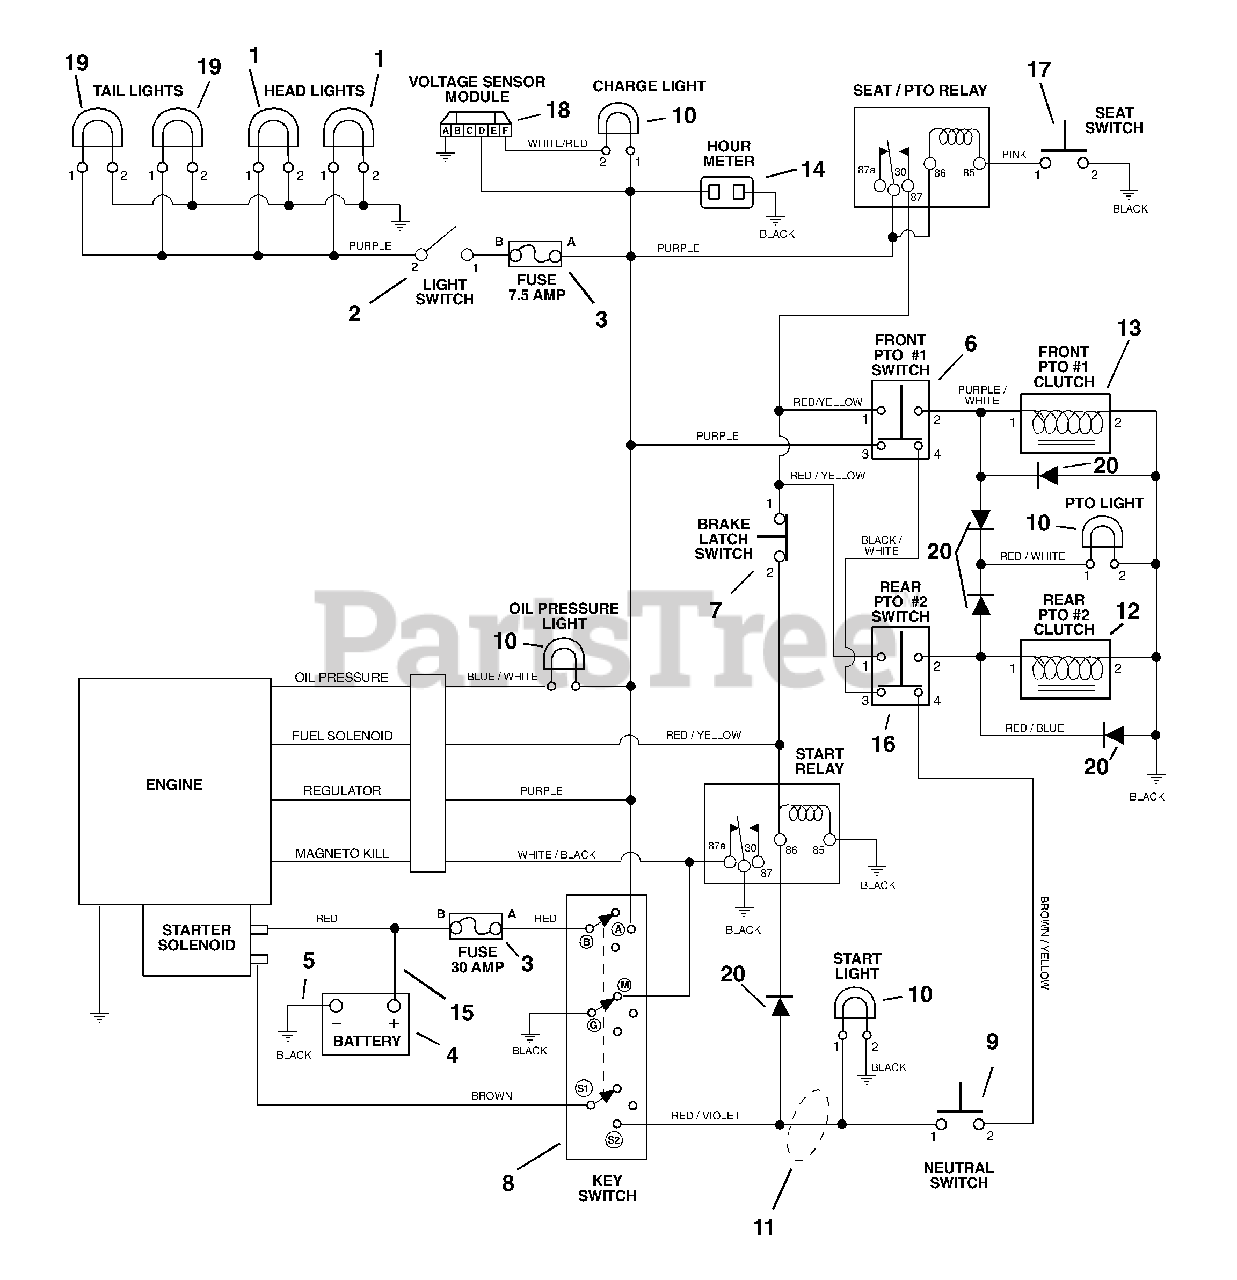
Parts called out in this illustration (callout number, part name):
1	HEADLIGHT- RH
1	HEADLIGHT- LH
2	SWITCH - LIGHT
3	7.5 AMP Fuse
3	30 AMP Fuse
4	BATTERY
5	CBL,NEGATIVE BATTERY 20.00
6	PTO KNOB/ SWITCH ASSY
7	SWITCH, INTERLOCK NC
8	KEY SWITCH
9	SWITCH- SINGLE POLE N.O.
10	#194 Bulb
11	HARNESS, WIRING
12	ELECTRIC CLUTCH
13	CLUTCH-ELEC. WARNER I-5215-62B
14	HOUR METER
15	CBL,BATTERY TO SOLENOID
16	CLUTCH SWITCH
17	SWITCH- SEAT
18	MODULE - VOLTAGE SENSOR
19	TAIL LIGHT ASSEMBLY W/BULLET
20	MOLDED DIODE PLUG 1 AMP
